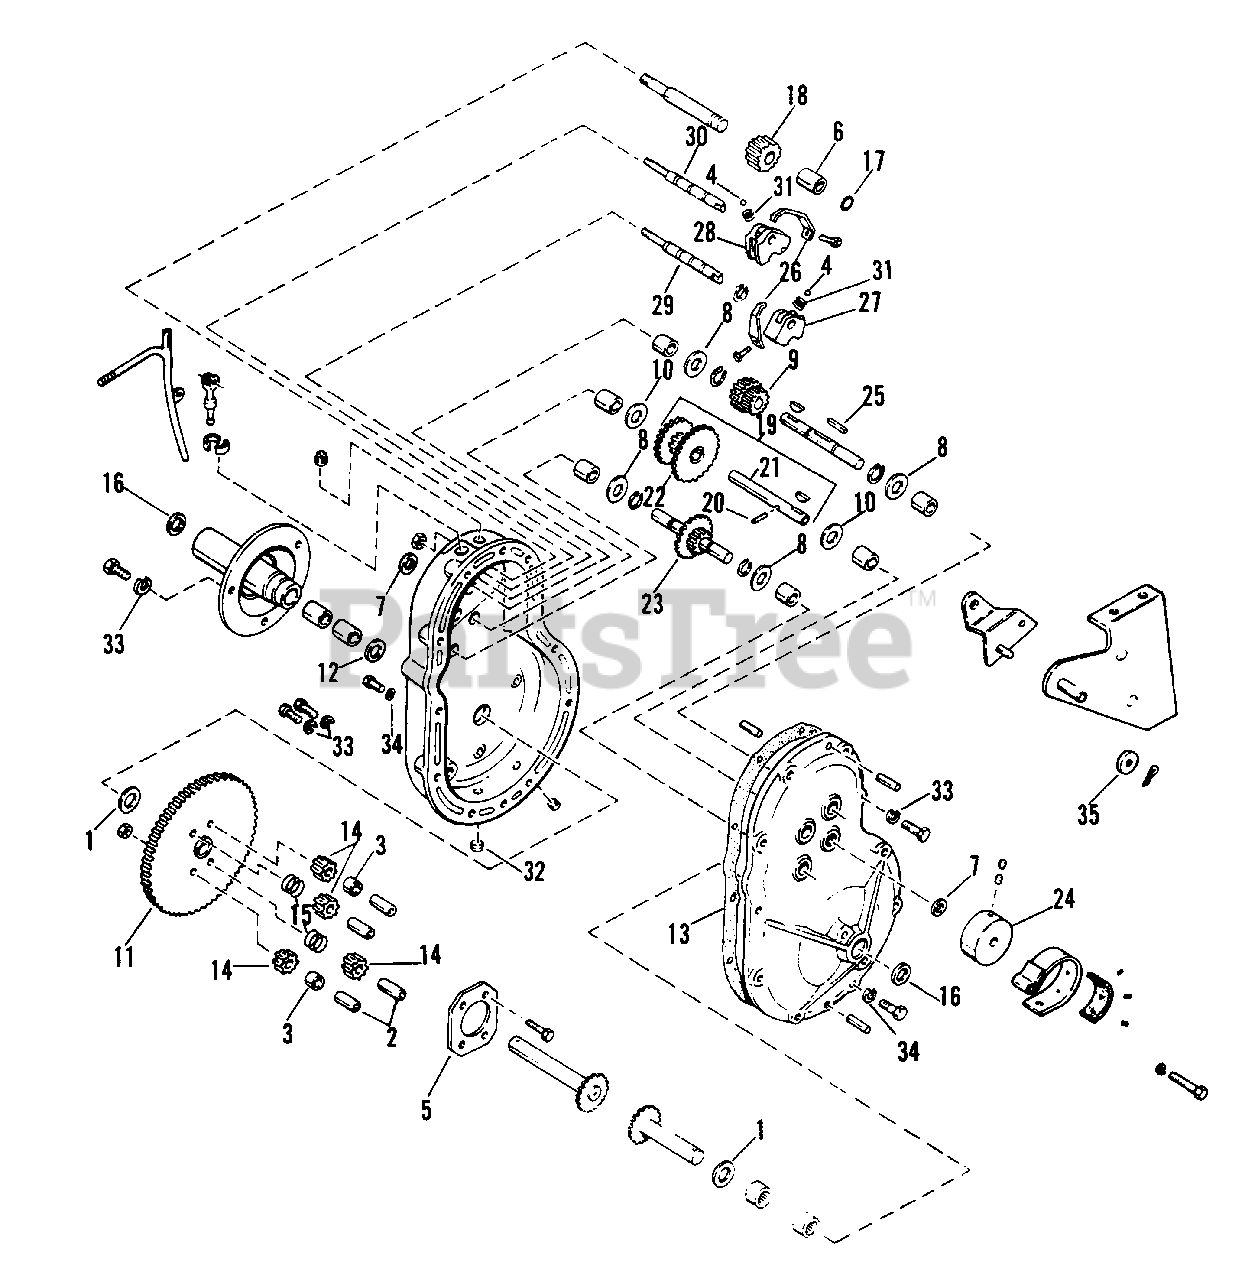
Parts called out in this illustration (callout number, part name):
2	SPACER, Pinion Diff.
3	SPACER, Diff.
4	BALL, Shiftlock
5	PLATE, Diff.
6	BEARING, Roller
9	PINION ASSY, Hi & Lo
11	GEAR ASSY, Drive
13	GASKET, Case
14	PINION, Diff.
18	PINION, Reverse
19	SHAFT & GEAR ASSY
20	DOWEL, Pin
21	SHAFT, Brake
22	CLUSTER GEAR ASSY
23	GEAR & SHAFT ASSY
24	DRUM, Brake
27	FORK, Shift Rev.
28	FORK, Shift 1 & 2
29	SHAFT, Shift, Rev & Lo
30	SHAFT, Shift Hi & Lo
32	PIPE, Plug, Sq Hd., 3/8
33	LOCKWASHER, Spring 3/8
34	LOCKWASHER, Spring 5/16
35	WASHER, Plain 1/4
